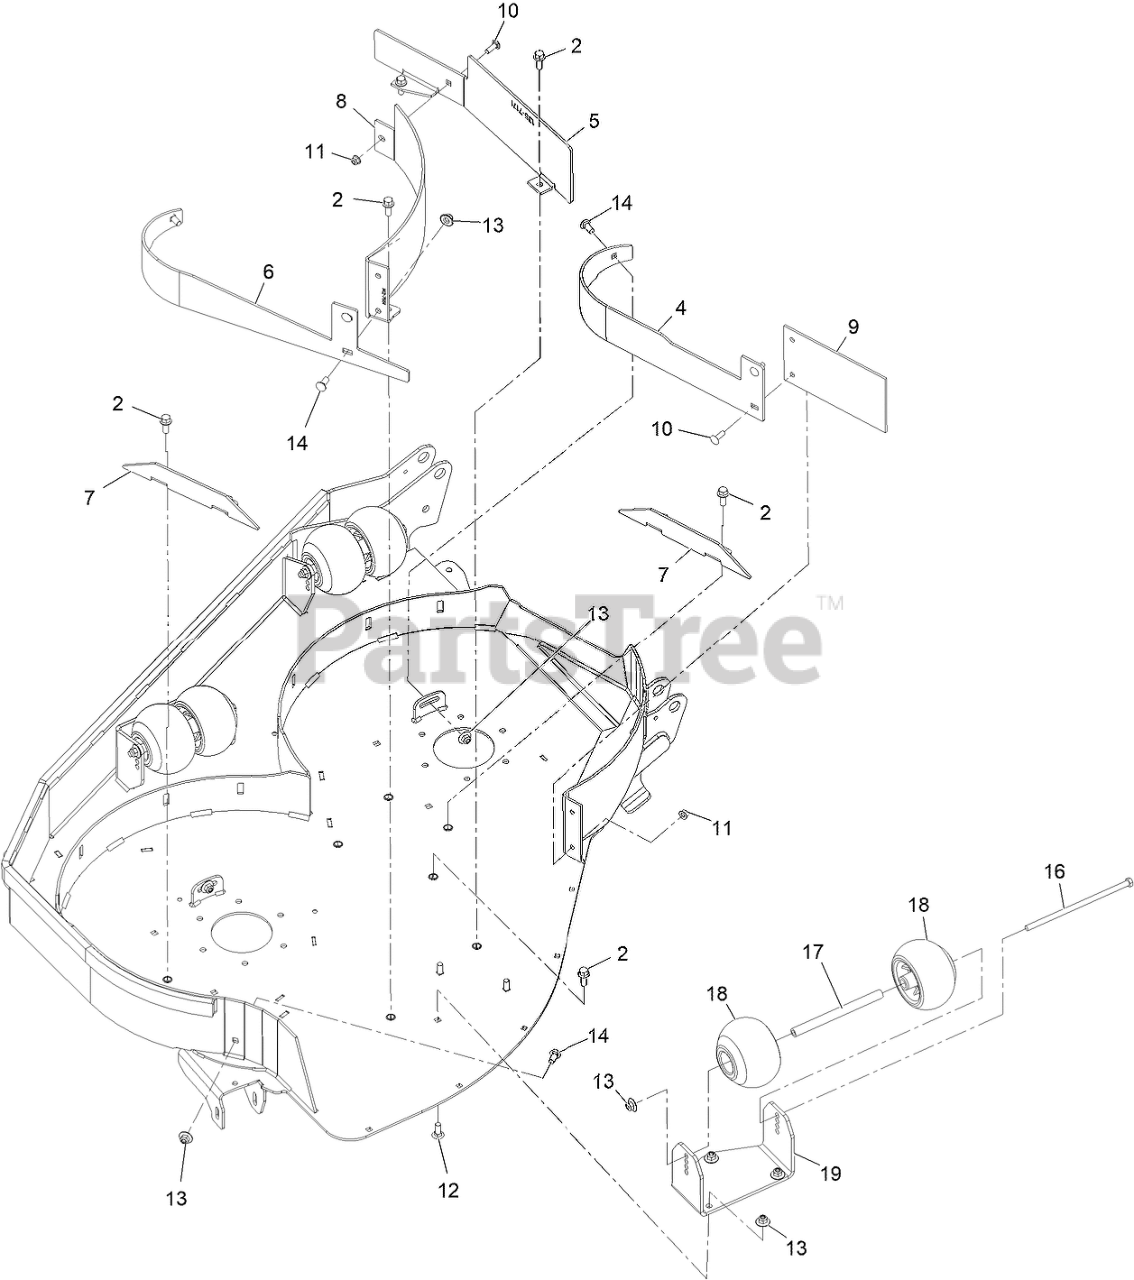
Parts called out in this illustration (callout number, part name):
2	SCREW-HHF
4	BAFFLE-DOGLEG, RH
5	BAFFLE-CTR
6	BAFFLE-DOGLEG, OUTSIDE
7	PLATE-BAFFLE STRAIGHT RH
8	BAFFLE-WING REAR CENTER
9	FLAP-RUBBER
10	SCREW-CARR
11	NUT-HF, NI
12	BOLT-CARR
13	Nut-Nyloc 3/8-16 Flg
14	BOLT-CARR
16	SCREW-HH
17	SPACER-WHEEL
18	ROLLER-SCALP, ANTI
19	PLATE-REAR AS BRACKET
